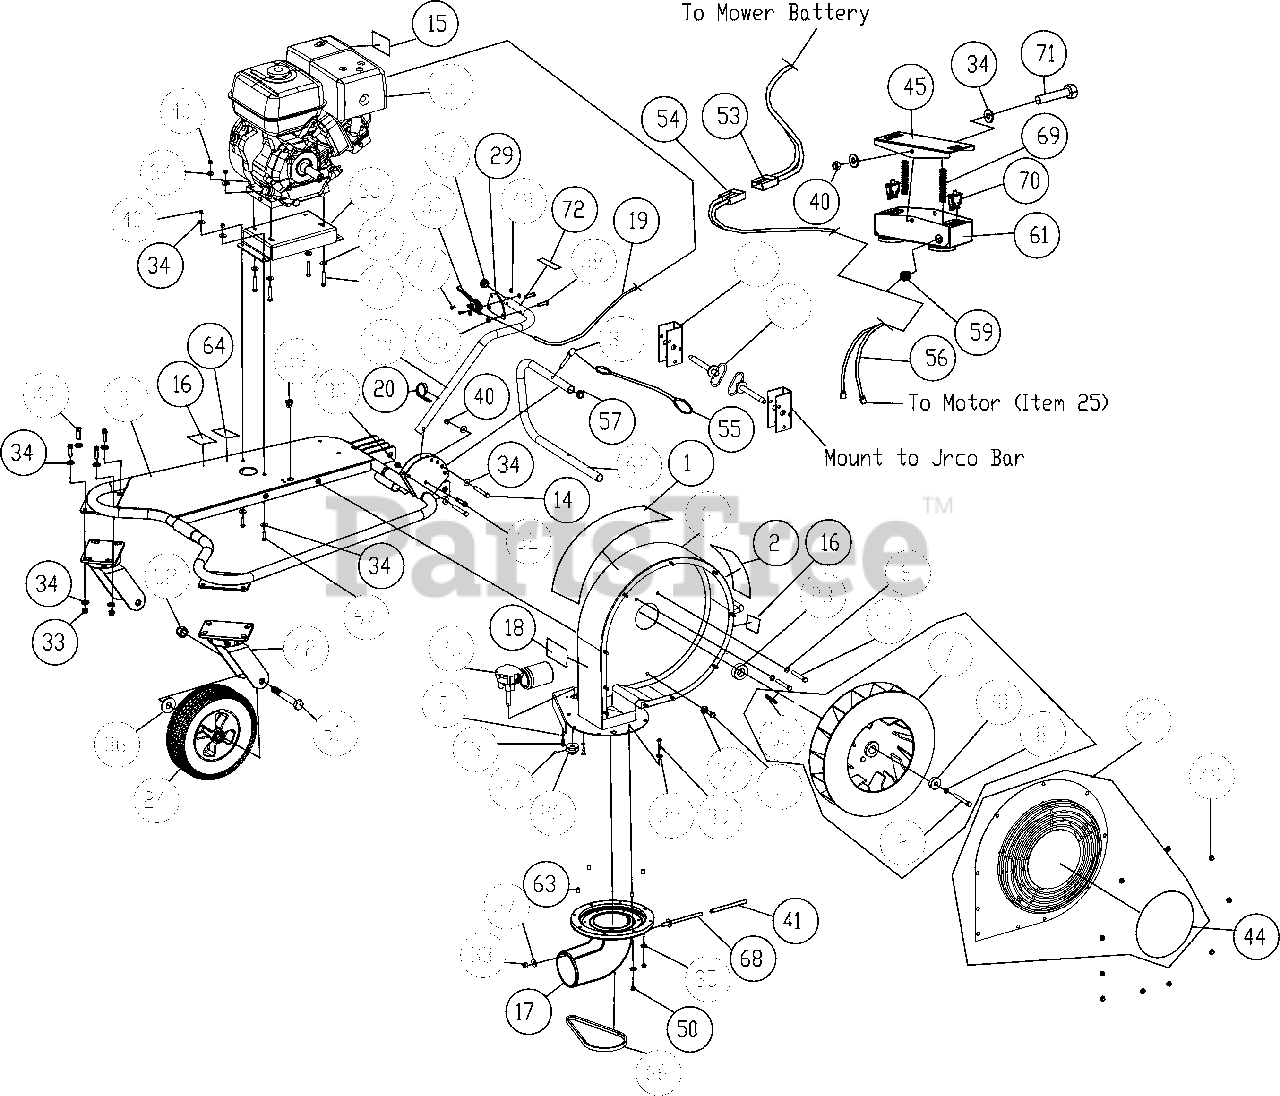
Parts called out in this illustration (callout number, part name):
1	LABEL LOGO FZ
2	LABEL WARNING FZ
3	FRAME WA FZ W/LABELS
4	JRCO BRACKET
5	ENGINE 13 HP HONDA
6	HOUSING WA FZ W/LABELS
7	IMPELLER ASSY FZ
8	WASHER LOCK 3/8" S/T MED
9	WASHER LOCK 1/4" S/T MED
10	SCREWCAP 3/8"-16 X 2 3/4" HCS ZP
11	SCREWCAP 3/8"-16 X 1" HCS ZP
12	SCREWCAP 3/8"-24 X 3 1/4" GR. 8 HCS
13	SCREWCAP 1/4"-28 X 3/4"
14	SCREWCAP 5/16" - 18 X 1 3/4" HCS ZP
15	LABEL GAS SHUT OFF
16	LABEL LIFT HERE
17	ELBOW EXHAUST ASSY
18	LABEL WARNING DEBRIS
19	CABLE THROTTLE 31.5
21	PLATE FRONT WA FZ W/LABEL
22	PIN HITCH 5/8" X 4 1/2"
23	SPACER CRANK FZ13H
24	WHEEL 12" W/3/4" BEARING
25	MOTOR 12V
26	PULLEY 1.63" OD X 7/16" BORE
27	SET SCREW 1/4" - 20 X .375 CUP POINT
28	THROTTLE STEM
29	THROTTLE PLATE
30	CONTROL THROTTLE
31	PIN 3/8" X 1 1/2" DETENT
32	BOLT SHOULDER 3/8" X 1"
33	NUT LOCK 3/8"-16
34	WASHER 5/16" FC
35	WASHER 1/4" FC
36	WASHER 3/4" FC
37	WASHER 3/8" FC
38	WASHER 1.5 OD X .453 ID X .5 THK
39	SCREWCAP 1/4"-20 X 1 1/4" HCS MED
40	NUT LOCK 5/16" - 18 HEX ZP
41	CAP INDICATOR RED
42	CASTER RIG 12"
43	SCREWCAP 3/8 - 16 X 1 1/4" HCS ZP
44	LABEL LOGO FORCE
45	SWITCH BOX TOP PLATE W/TREAD TAPE
46	NUT LOCK 5/16" TH HT HEX ZP
47	SCREW MACH #10-24 X 1/2"
48	NUT LOCK #10 - 32
49	NUT FLANGE 5/16" - 18 ZP
50	NUT LOCK 1/4 - 20
51	SCREWCAP 3/4 - 10 X 5 1/2"
52	NUT LOCK 3/4"-10 ZP
53	HARNESS WIRE FZ BATTERY
54	HARNESS WIRE ROTATOR SWITCH
55	LANYARD PLASTIC 10"
56	HARNESS WIRE CONTROL
57	PLUG TUBE INSERT 1" OD
58	SCREW BUTTON HEAD 5/16-18 X 1 1/4"
59	STRAIN RELIEF
60	KEY 1/4" SQ X 2.25"
61	SWITCH BOX WA
62	TUBE KICK STAND
63	STAND OFF NOZZLE FZ
64	LABEL MADE IN USA
65	STAND OFF ENGINE FZ WA
66	BELT GATES TRUFLEX 1260
67	SCREWCAP 5/16" - 18 X 1 1/4" HEX ZP
68	INDICATOR DIRECTION WA
69	SPRING .578 OD X 3.16 LONG
70	SWITCH ROTATOR
71	SCREWCAP 5/16 -18 X 4 1/2"
72	LABEL THROTTLE CONTROL
